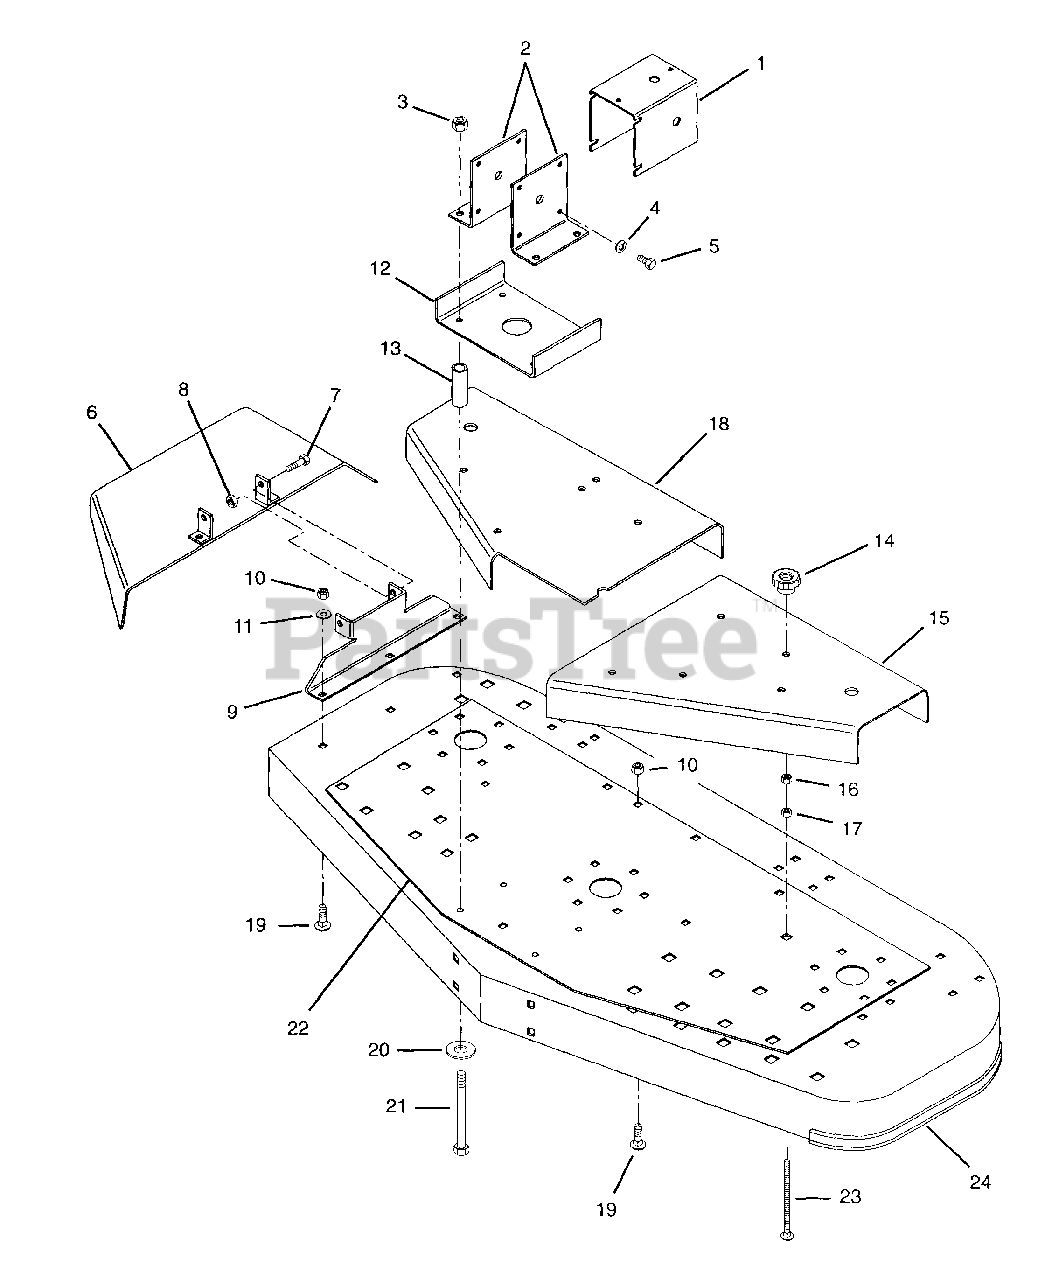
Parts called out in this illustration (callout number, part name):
1	Shield, U-Joint
2	Bracket, Gearbox Mounting
3	Nut-Locking-Nylon .50-13 Grade 5
4	Washer-Lock .375 x .094
5	Bolt-Hex .380-16 x .875
6	Weldment, Discharge Chute
7	Bolt-Hex .25-20 x .875
8	Nut-Locking-Nylon .250-20 Grade 2
9	Bracket, Discharge
10	Nut-Locking-Nylon .375-16 Grade 2
11	Washer-Flat-Steel .406 x .812 x .065
12	Plate, Support
13	Spacer .562 x 1.00 x 2.00
14	Knob
15	Cover, Belt Silkscreen
16	Nut-Locking-Nylon .312-18 Grade 2
17	Nut-Jam .312-18
18	Cover, Belt Right Hand
19	Bolt-Round Head Square Neck .38-16 x 1.0
20	Washer-Flat-Steel .531 x 1.062 x .095
21	Bolt-Hex .50-13 x 3.75
22	Plate, Deck Support
23	Bolt-Round Head Square Neck .31-18 x 4.0
24	Weldment, 60" Mower Deck
